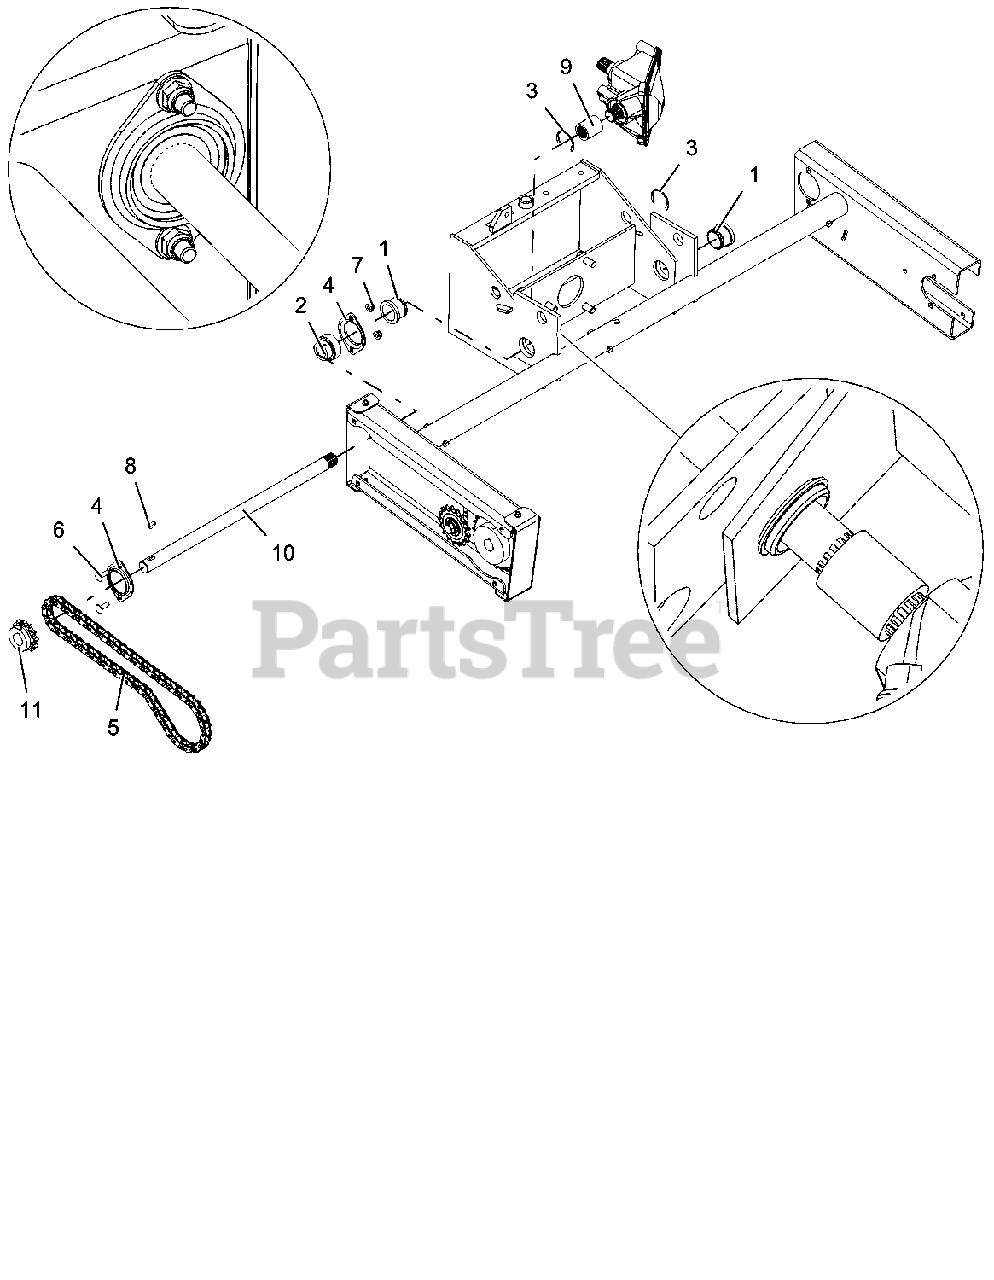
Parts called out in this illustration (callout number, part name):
2	BRG/W COLLAR 1.0 X 2.047 X.844
3	SHAFT, RING C
4	MTG-FLG 2 HOLE 52MM X 3.75
5	CHAIN, ROLLER 64 PITCHES #50
6	BLT,RHSN .31-18X1.00 G5 ZC120
7	NUT,LK-NYL-FLG .31-18 G5ZC120
8	KEY-WDRF .25X.750X.313 SAE91
9	CPLG 1.6X1.37
10	SHAFT, OUTPUT SPLINE
